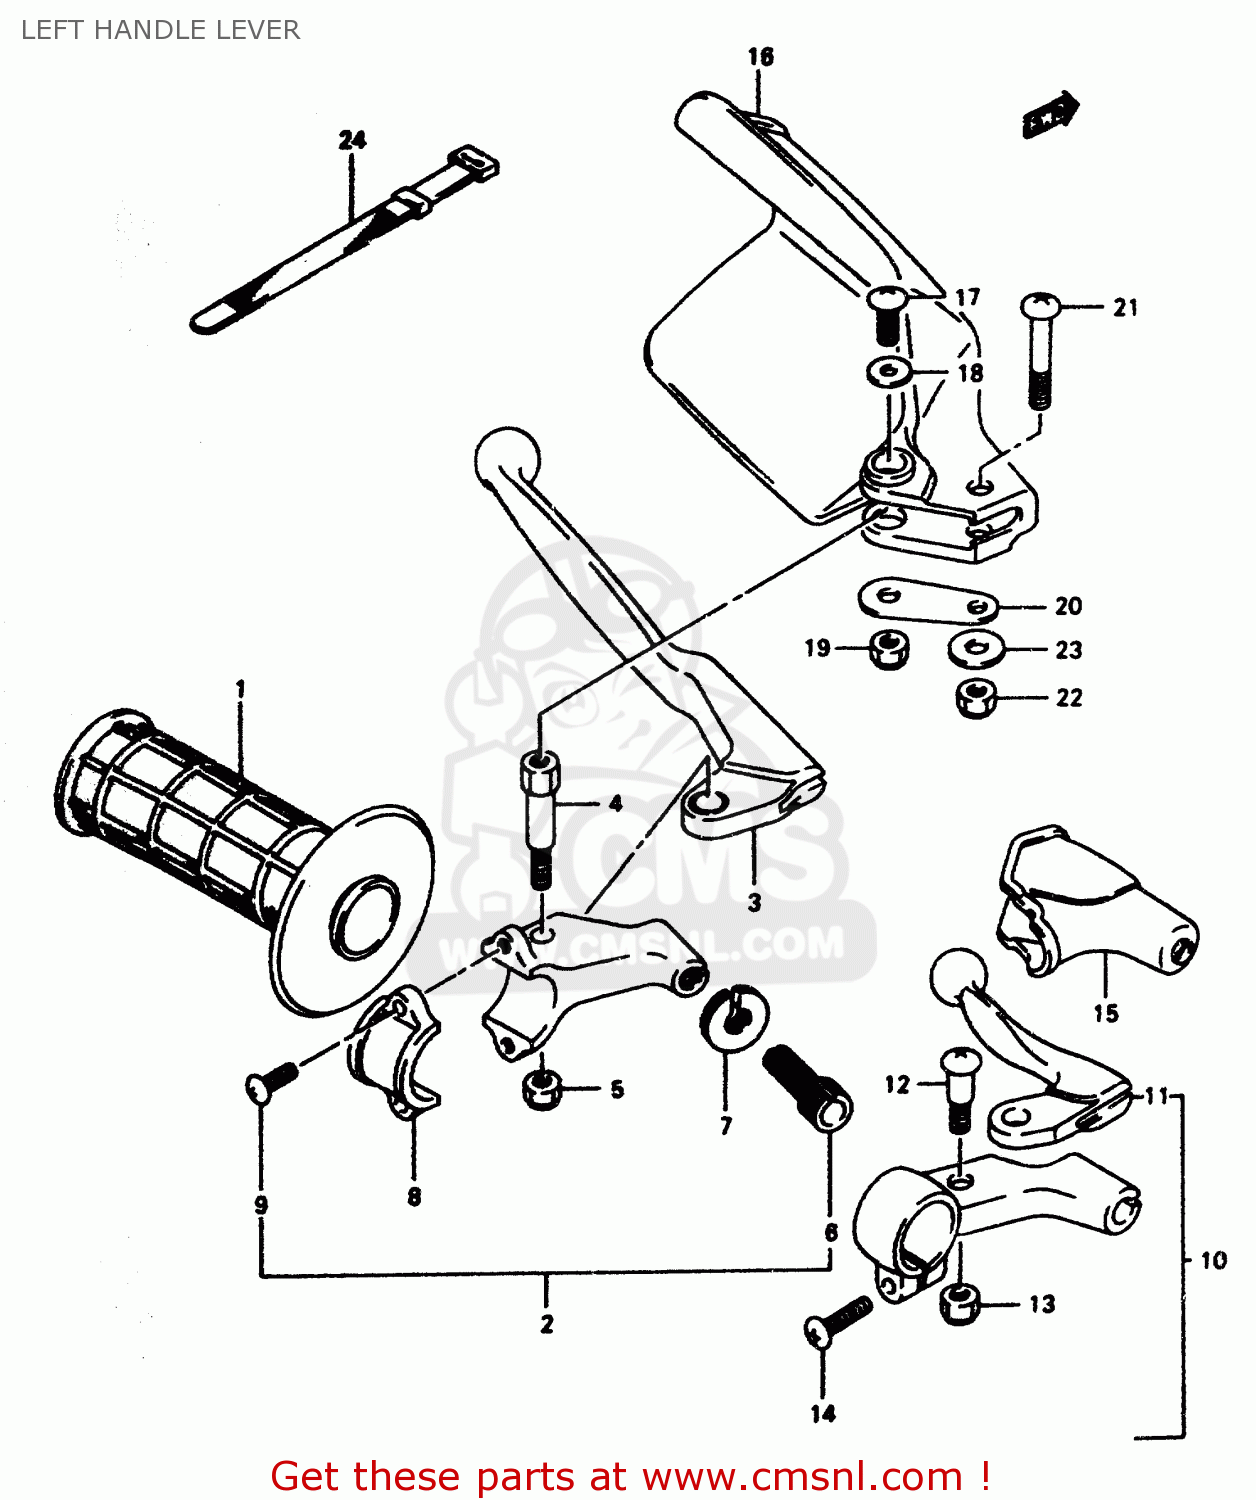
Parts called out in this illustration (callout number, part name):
1	GRIP,L
2	LEVER ASSY,CLUTCH
3	LEVER,CLUTCH
4	BOLT,LEVER SET
5	NUT 6MM
6	ADJUSTER,CABLE
7	NUT
8	BRACKET,CLUTCH LEVER HOLDER
9	SCREW(5X14)
10	LEVER ASSEMBLY,DECOMPRESSION
11	LEVER,DECOMP
12	BOLT,LEVER PIVOT
13	NUT
14	SCREW, 6X20
15	COVER,DECOMP LEVER DUST
16	COVER,KNUCKLE,L
17	SCREW
18	WASHER (5.5X16X1.2)
19	NUT 6MM
20	PLATE,KNUCKLE COVER,L LWR
21	SCREW(6X35)
22	NUT 6MM
23	WASHER (6.5X17X1.6)
24	CLAMP(L:120)
